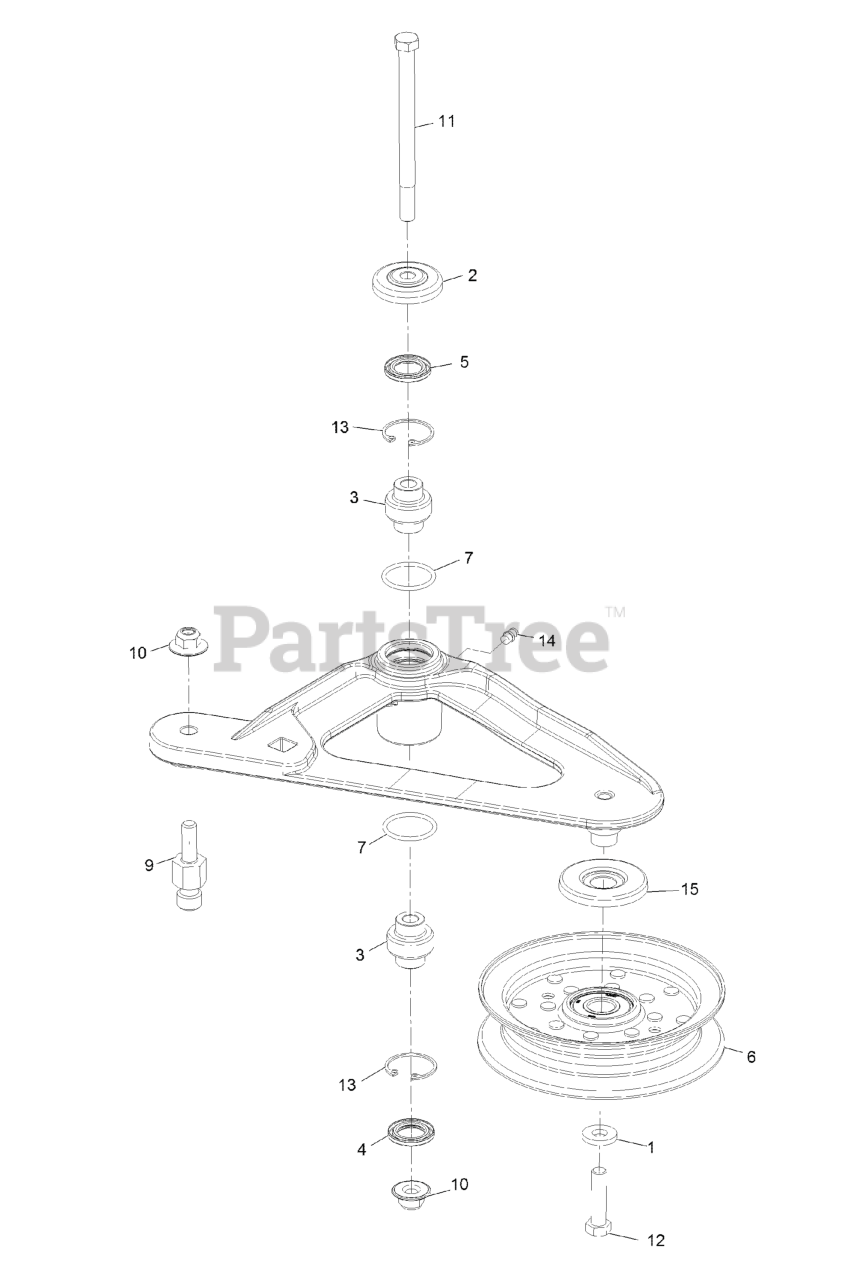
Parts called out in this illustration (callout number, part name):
2	GUARD-TOP
3	BEARING-SPHERICAL
4	SEAL-LIP, DOUBLE
5	SEAL-LIP, SINGLE
6	IDLER-PULLEY, FLAT
9	PIN-SPRING, ANCHOR
10	Nut-Nyloc 3/8-16 Flg
11	SCREW-SHOULDER, HH
12	SCREW-HH
13	RING-SNAP
14	FITTING-GREASE
15	SHIELD-GUARD, DUST
